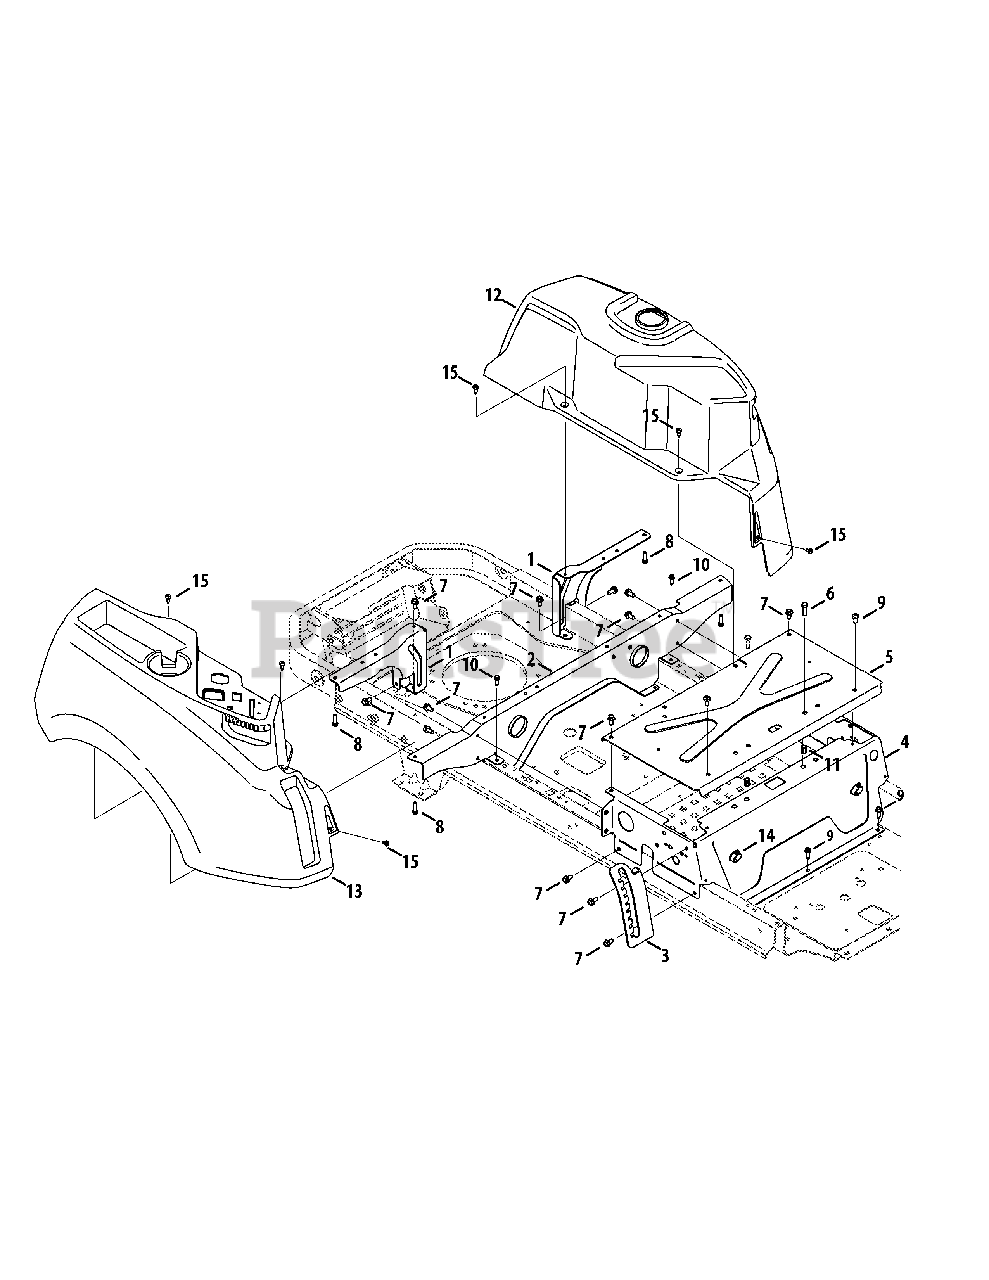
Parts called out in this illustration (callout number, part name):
1	Rear Tank Bracket
2	Rear Seatbox Brace
3	Height Index Bracket
4	Seat Frame
5	Seatbox Plate
6	Hex Cap Screw 5/16-18 x 1.00
7	Hex Washer Screw 5/16-18 x .750
8	Hex Washer Screw 5/16-14 x 1.00
9	Self Tapping Screw 5/16-18 x .750
10	Hex Washer Screw 5/16-18 x .50
11	Nut 5/16-18
12	LH Console
13	RH Console (w/RMC)
14	Plastic Plug
15	Shoulder Screw 1/4-20
16	Hex Wash Hd TT Scr. 3/8-16 x 1.0
17	Hex Wash Hd TT Scr. 5/6-18 x .5
